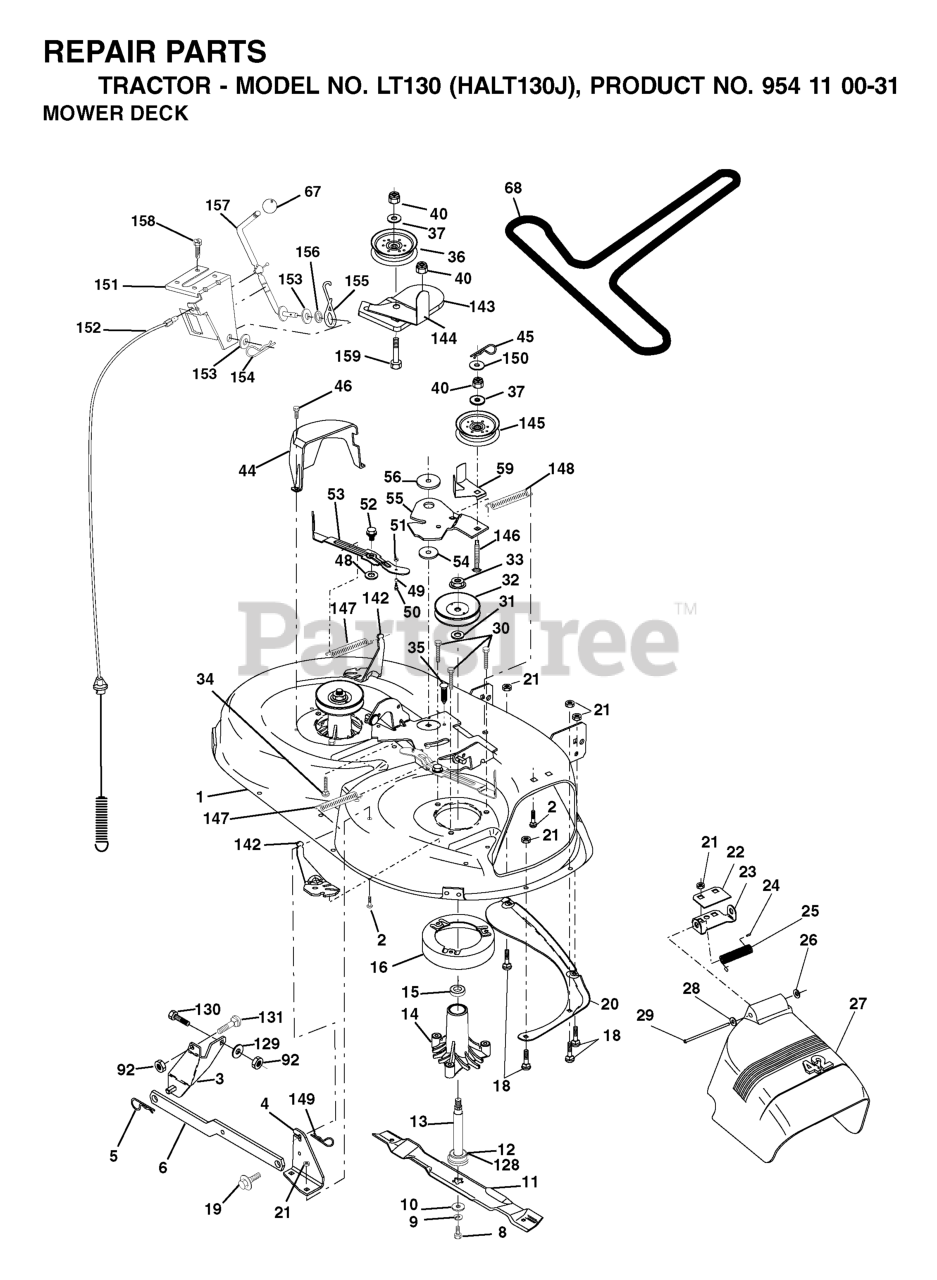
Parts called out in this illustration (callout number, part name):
1	Battery 12 Volt 25 Amp
2	BOLT.HEX.1/4.X.3/4.DICHROMATE
8	TRAY.BATTERY BOX.FRONT
16	SWITCH INTERLOOK PUSH-IN
21	HARNESS.LIGHT W/4152J BULBS
24	CABLE.FRBATT.W/WIRE.8GA.8
25	CABLE.STARTER.8GA.17.5
26	FUSE 20AMP
27	NUT
28	CABLE.GROUND.21"BLK.8GA.90T
29	SWITCH.SEAT.DELTA.OPC.
30	SWITCH.IGN.DELTA.W.LGH.ROS
33	KEY.CHAIN.BLISTER.PACK.GEN.USA
40	HARNESS.IGN.DASH.HUSQ/PRED
41	SCREW
42	TERMINAL COVER
43	SOLENOID.W/BRASS.PLUNGER
46	GUAGE.SRVCMNDR.HRMTR.
50	RP.PTO.SWITCH.8 TERMINAL.BLACK
55	SCREW 5/16"
59	OUTLET.12-VOLT
71	HARNESS-CHASSIS SUB
79	BULB HOLDER ASM.
90	COVER.TERMINAL.BATTERY
99	SCREW HEXWSHR 1/4-20X3/4
102	HARNESS PIGTAIL PCH TEX ROS
103	HARNESS PIGTAIL 12V OUTLET
105	REVERSE SWITCH
142	CHARGE.PORT.PIGTAIL HARNESS
143	CHARGE.PORT
